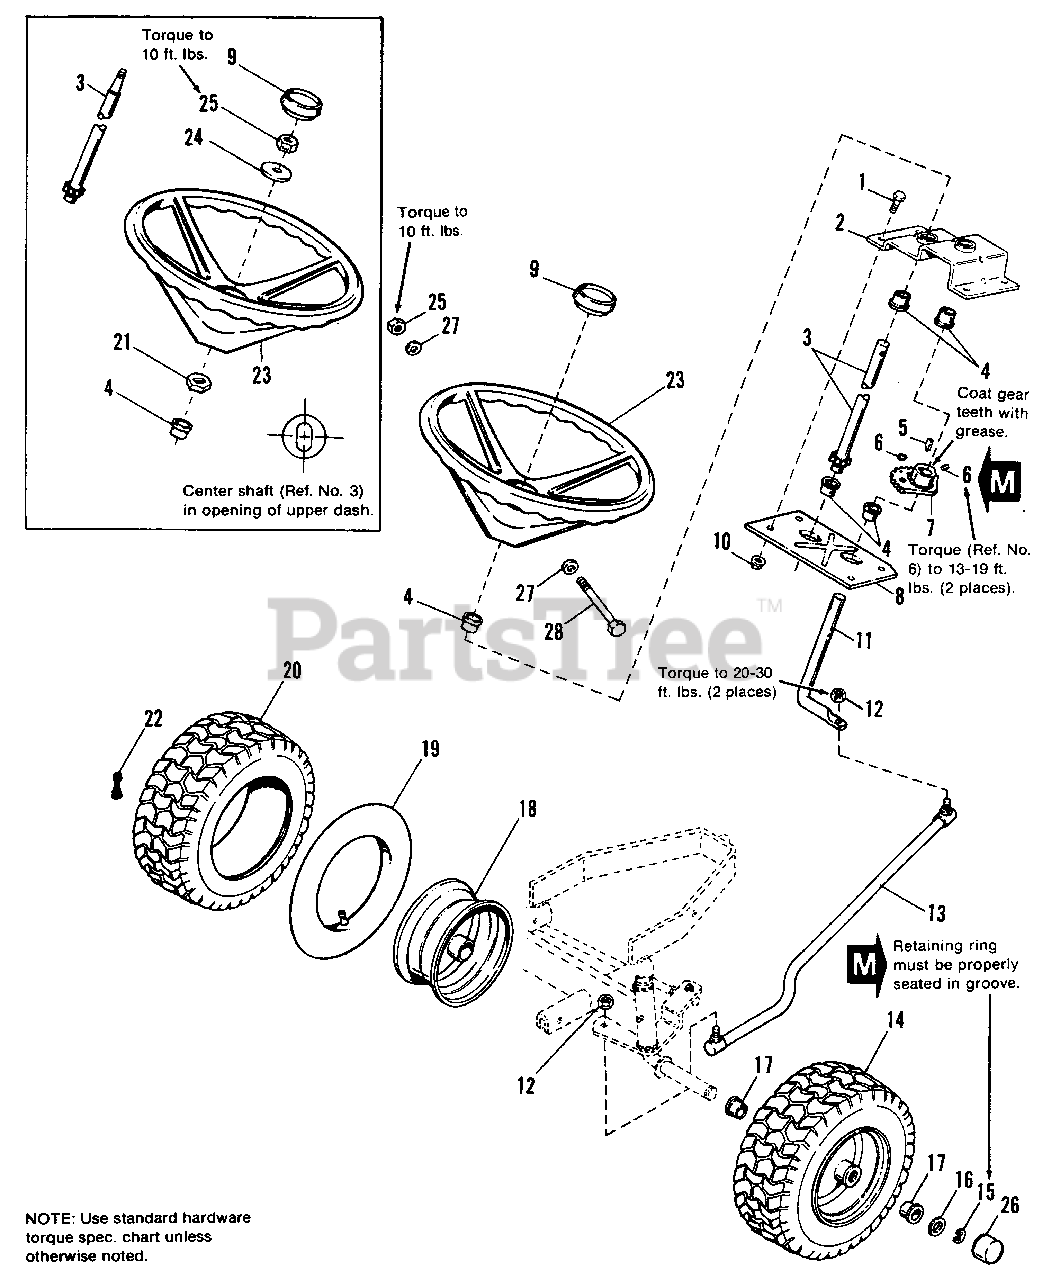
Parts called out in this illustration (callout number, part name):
1	CAPSCREW, Hex Hd., 5/16-18 x 3/4
2	PLATE, Steering
3	SHAFT ASSY., STEERING
6	SETSCREW, 5/16-18 x 1/2
7	GEAR, Steering
8	PLATE, Base, Steering
9	CAP, Steering Wheel
10	LOCKNUT, Hex, Flange, 5/16-18
11	ROD, Steering
12	NUT, Special, 3/8-24
14	WHEEL & TIRE ASSY.
18	WHEEL ASSY.
19	TUBE, 4.10/3.50-6 (For Service Only)
20	TIRE, (Carlisle) 15 x 6.00-6
21	WASHER, Hex
22	VALVE STEM & CAP
23	WHEEL, Steering (Incl. Ref. No. 21)
23	WHEEL, Steering, Bolt Mounted
24	WASHER, Compression
25	LOCKNUT, Hex, 5/16-18
26	HUB CAP, Threaded
27	WASHER, Plain
28	BOLT, 5/16-18 x 3-1/2
